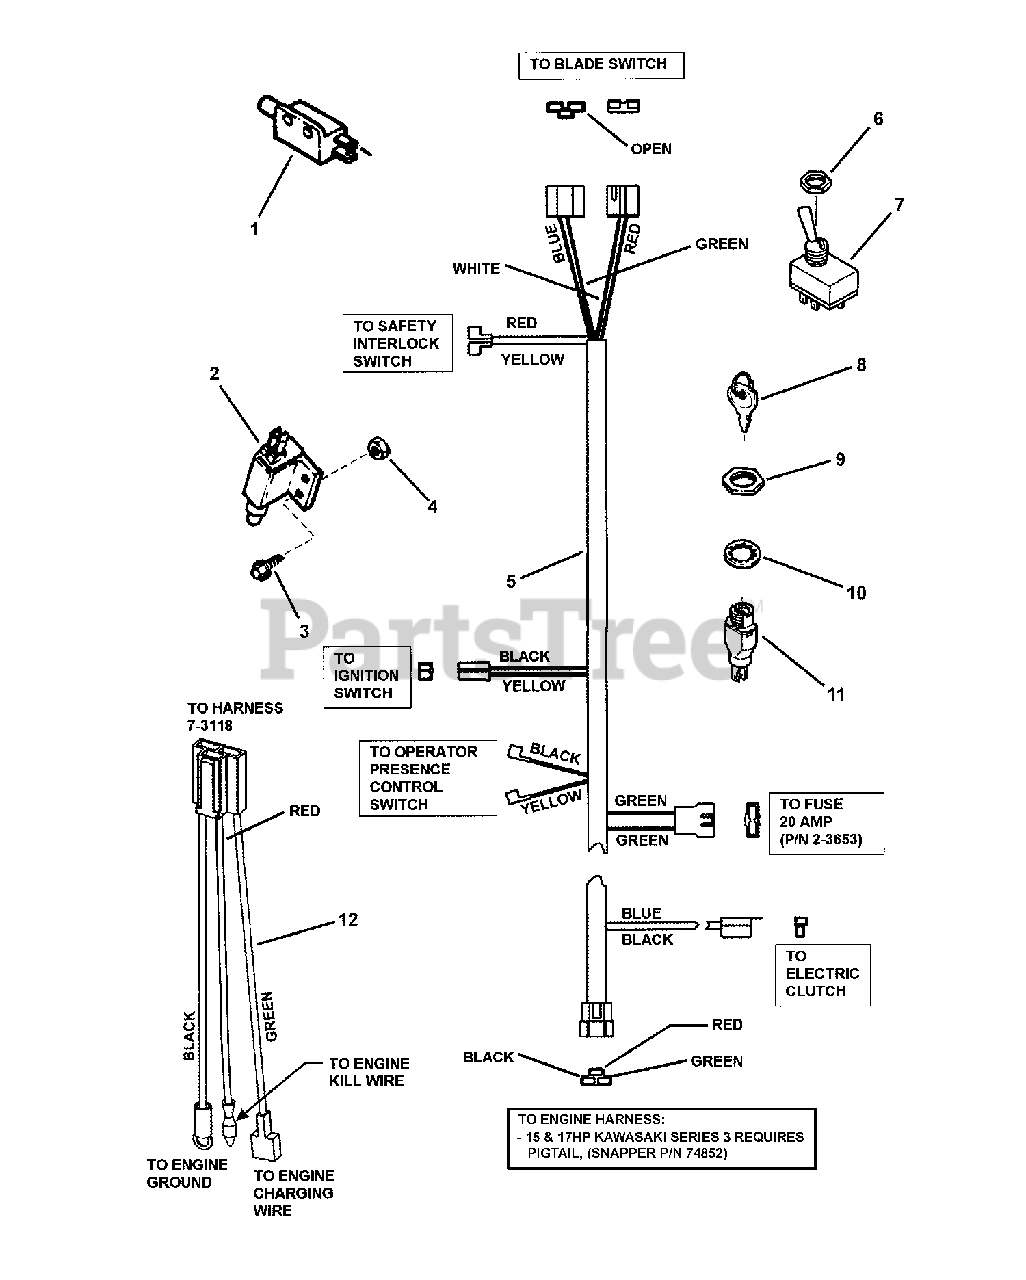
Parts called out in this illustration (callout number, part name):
1	SWITCH, Single Pole, LG-1, N.C.
2	SWITCH, Interlock, Sealed, SPST, N.C.
3	SCREW, #10-32 x 5/8" Hex Machine
4	NUT, #10-32 Hex Nyloc
5	WIRING HARNESS
6	NUT, 1/2-27 Hex (Special)
7	SWITCH, Toggle (H671A)
8	IGNITION KEY (Pair)
9	NUT, 5/8-32 Hex (Ignition Switch)
10	WASHER, 5/8" Internal Tooth Lock
11	SWITCH, Ignition, 2-Pole
12	HARNESS, Wiring Pigtail
